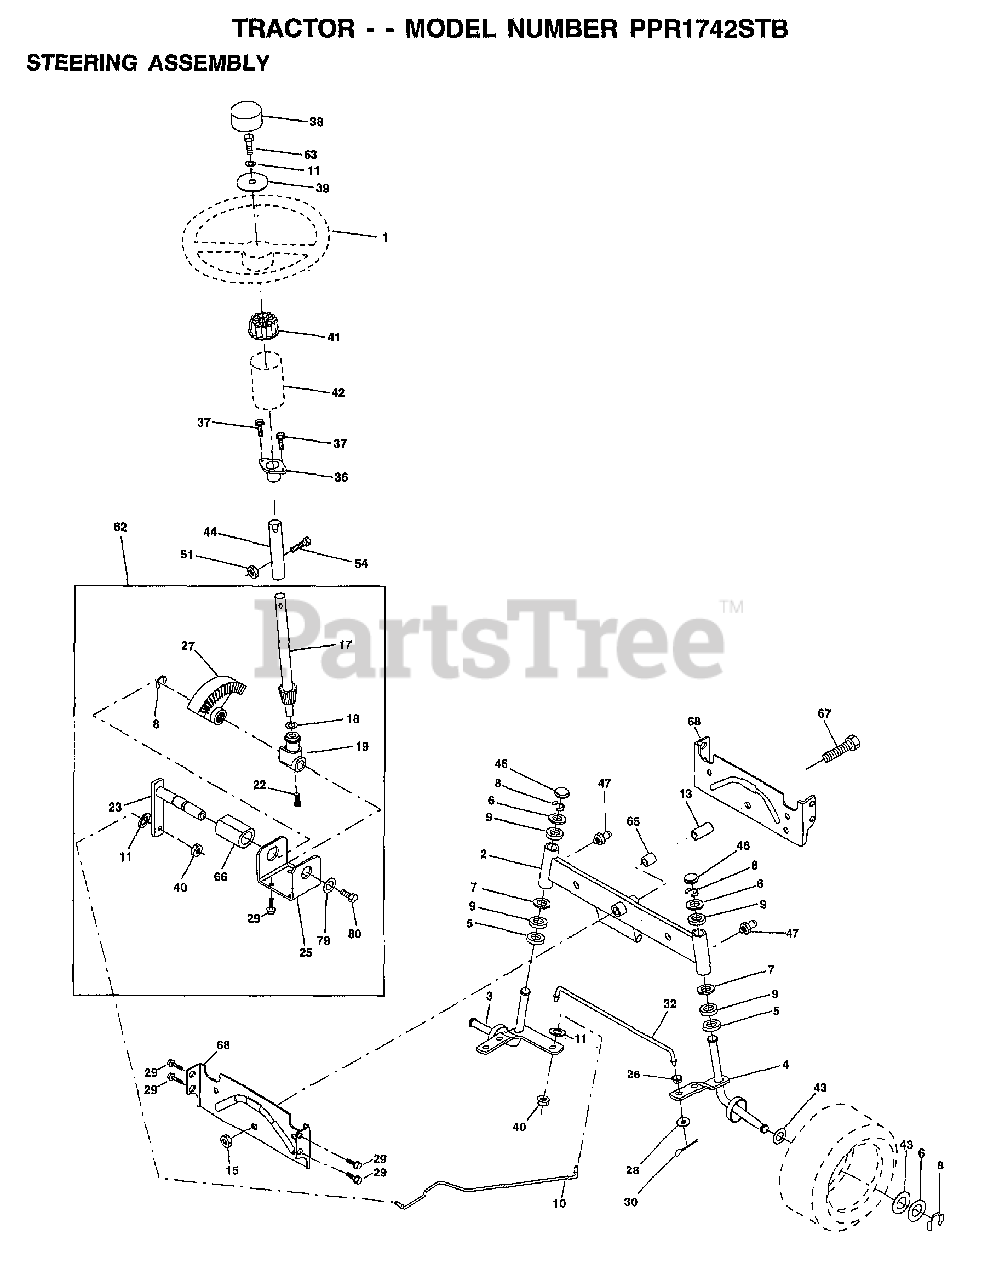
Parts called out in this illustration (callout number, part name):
2	AXLE ASM
3	SPINDLE.ASM.LH
4	"SPINDLE ASM,RH"
5	WASHER .T
6	WASHER
7	WASHER
8	RING
9	COL. SRTG. BEAR.
10	DRAGLINK-STAMPED
11	LOCKWASHER
13	BEARING AXLE
15	"NUT-LOC,FLANGE LT"
17	SHAFT ASM STEERIN
18	THRUST WASHER
19	SUPPORT.SHAFT.STEER
22	SCREW.HX.WSH.HD
23	SHAFT.ASM.PITMAN
25	BRKT-STEERING
26	BUSHING.DRAGLINK
27	GEAR SECTOR
28	WASHER
29	SCREW
30	COTTER PIN
32	TIE ROD
36	BUSHING.STEERING
37	"SCREW-TT,10-32 FL"
38	"INSERT,STR WHEEL"
39	WASHER
40	GRIPCO NUT
41	ADAPTER LT
42	BOOT.STEERING.DASH.P/L
43	WASHER
44	EXT SHAFT STEERIN
46	CAP
47	ZERK M
51	NUT
54	BOLT
62	KIT.STEER.ASM
63	BOLT
65	SPACER AXLE
66	"BEARING-ARM,PITMA"
67	BOLT
68	BRACE AXLE
79	WASHER
80	BOLT.HX.NYLON3/8-16X3/
